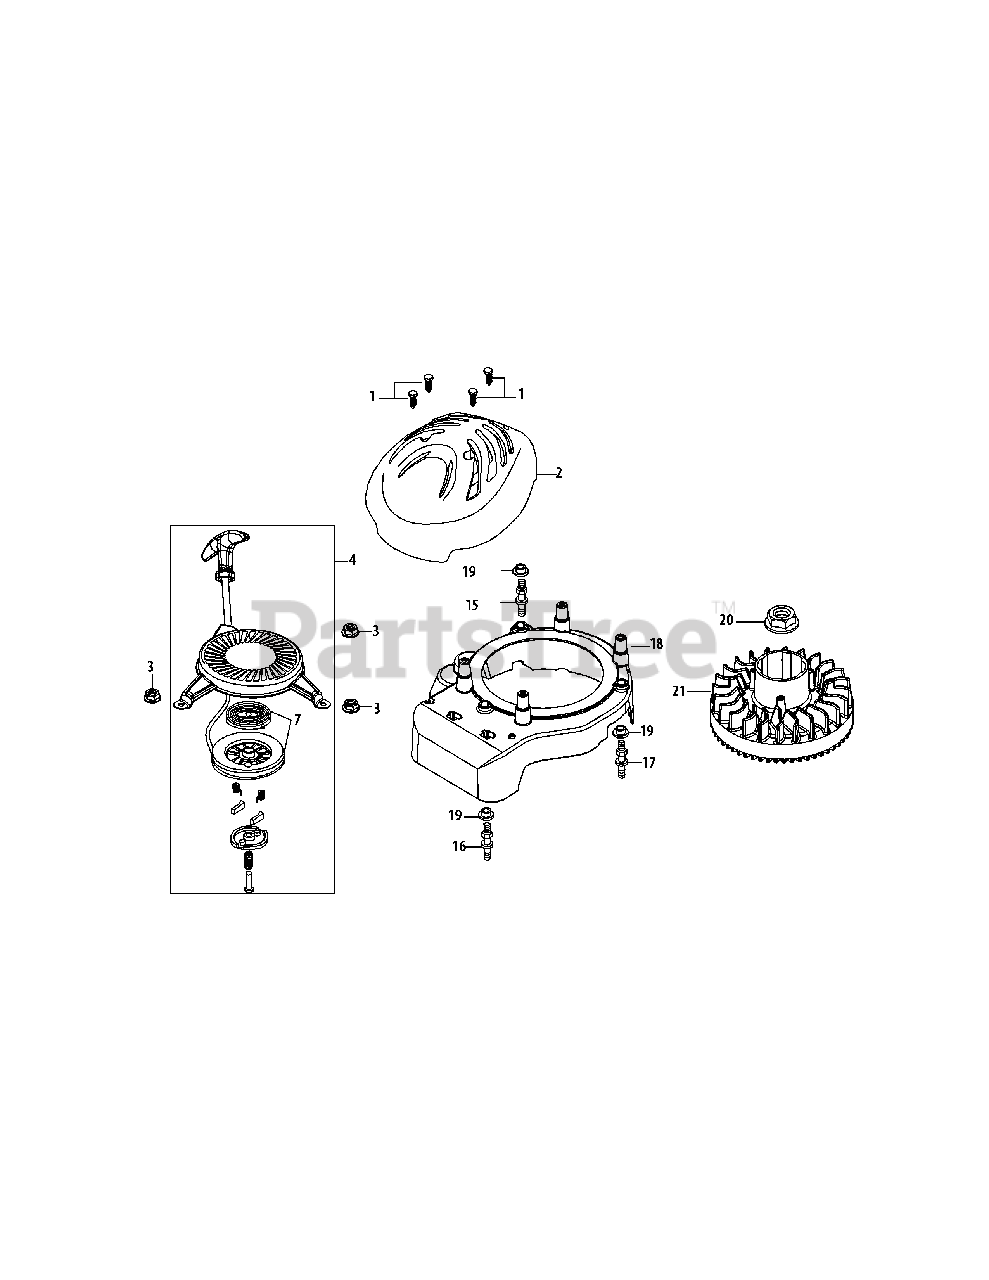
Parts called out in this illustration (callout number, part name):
1	Self-Tapping Bolt, #12-16 x 1"
3	Nut M6 X 10 Mm
4	Recoil Starter Assembly
7	Recoil Spring And Pulley Assy
15	Starter/Shroud Stud Left/Black
16	Starter/Shroud Stud Front/Yellow
17	Starter/Shroud Stud Right/White
18	Inner Shroud
19	Engine Shroud Spacer
20	Flywheel Nut M14×1.5
